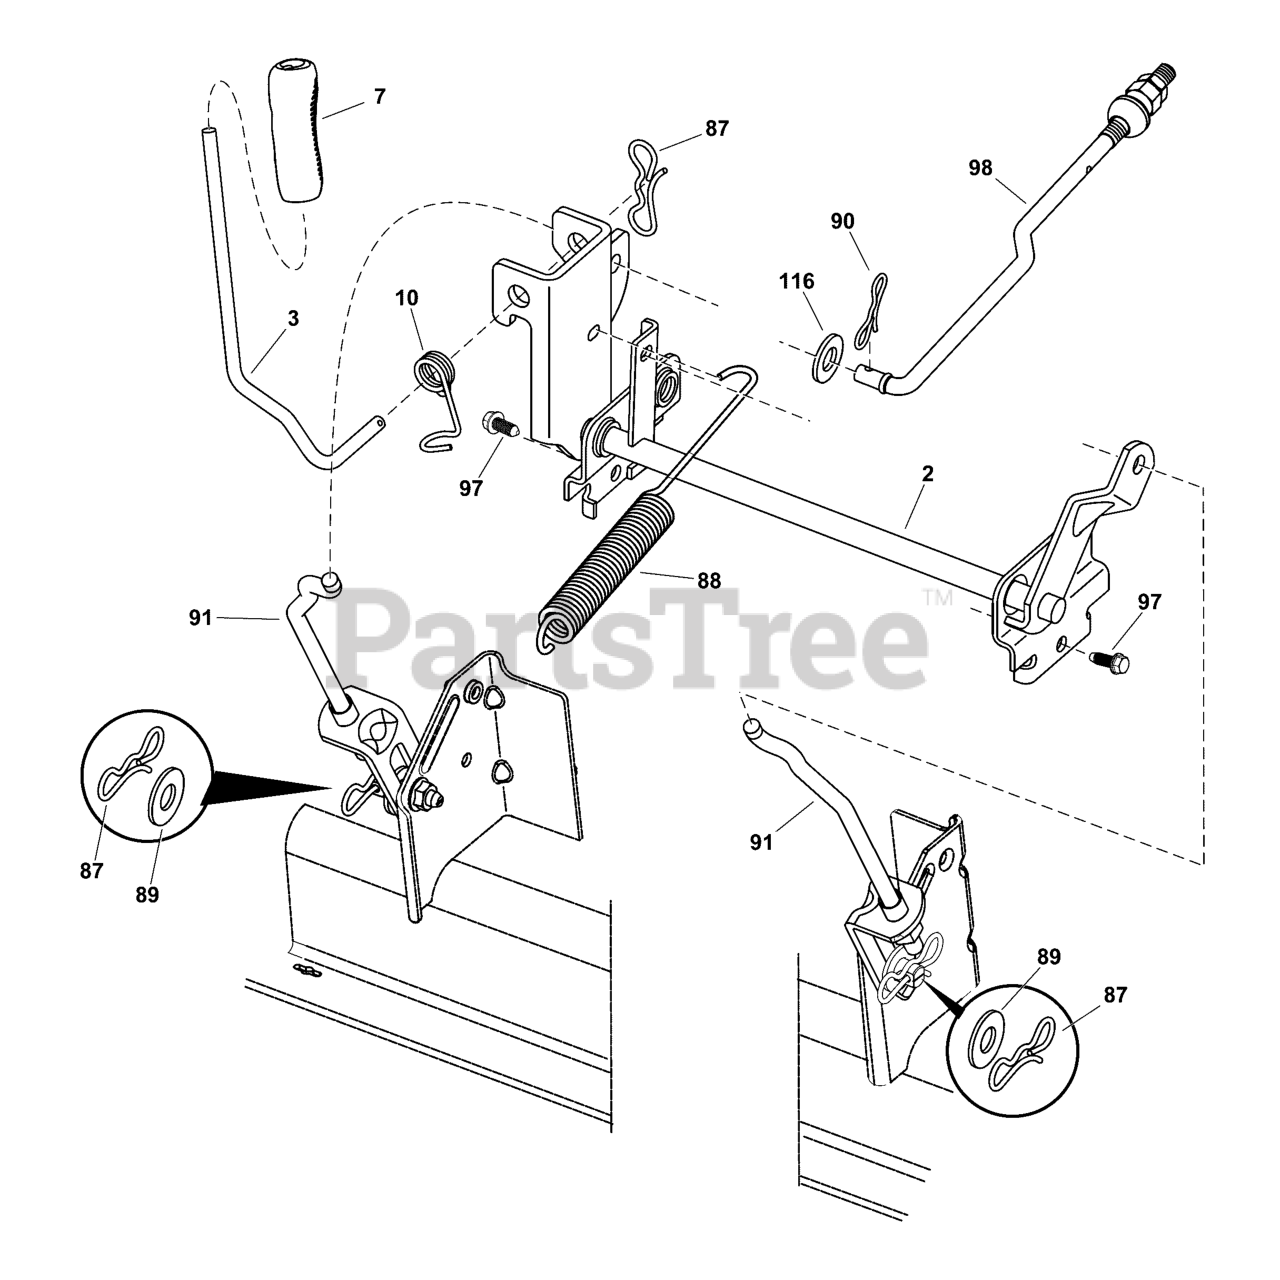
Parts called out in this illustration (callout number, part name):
2	Shaft Asm., Lift
3	Lever Asm., Lift RH
7	Grip, Lever
10	Spring Torsion
87	Pin Cotter 7/16 Bow Tie Lock
88	Spring Lift Assist
89	Washer Clear Zinc
90	Pin Cotter 5/16 Bow Tie Lock
91	ROD, Lift
97	Screw 3/8-16 x .75 Smgml Tap/R.Z
98	ROD, Link
116	WASHER, 15/32 x 15/16 x 16 Ga.
